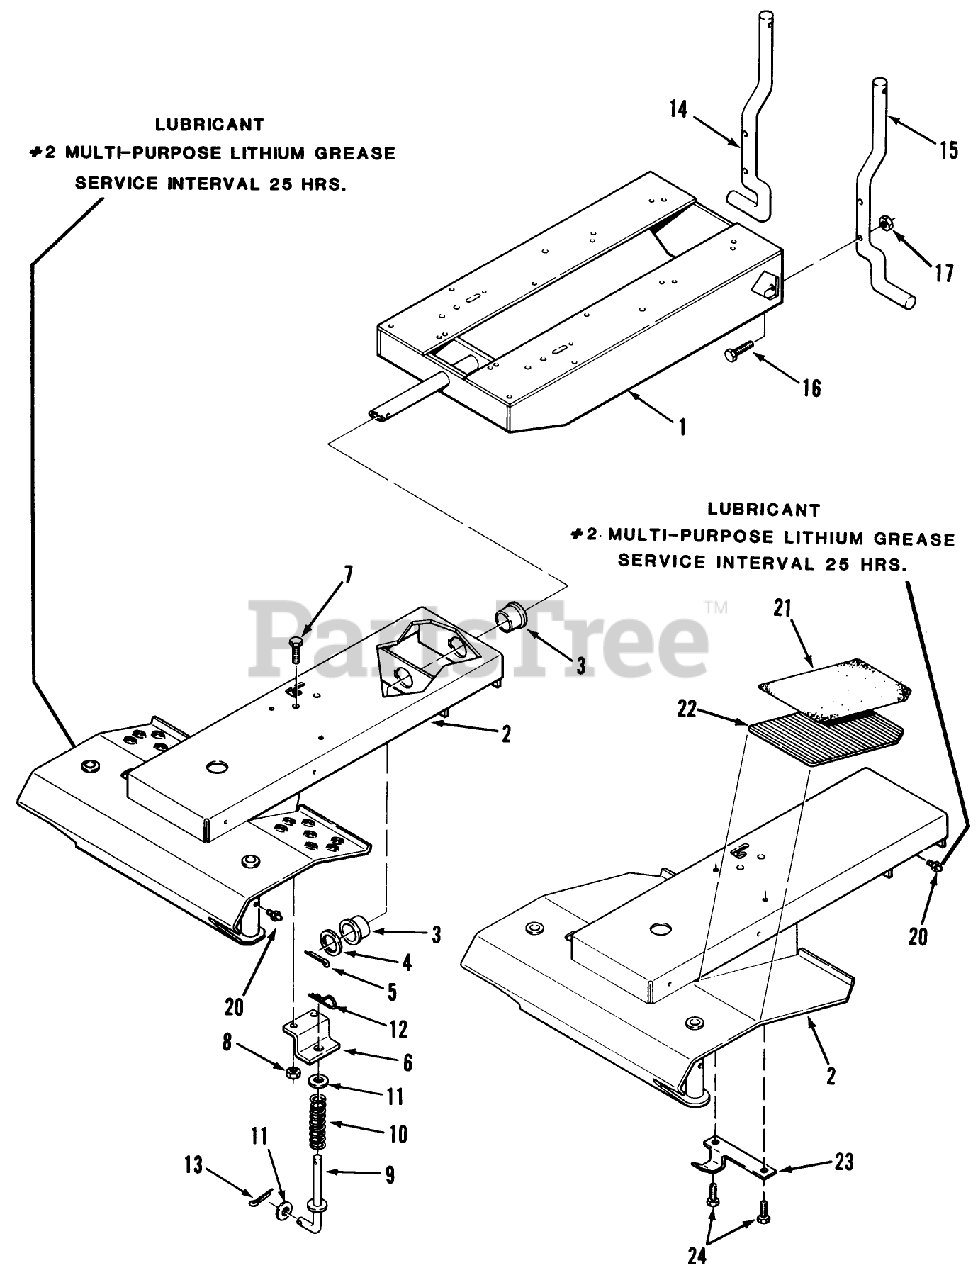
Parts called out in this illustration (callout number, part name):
1	ASS'Y-FRAME REAR *R
10	SPRING-COMPRESSION
12	Hairpin Cotter
14	REAR ROD RH *B
15	REAR ROD LH *B
22	PAD FOOTREST RH
24	Screw
